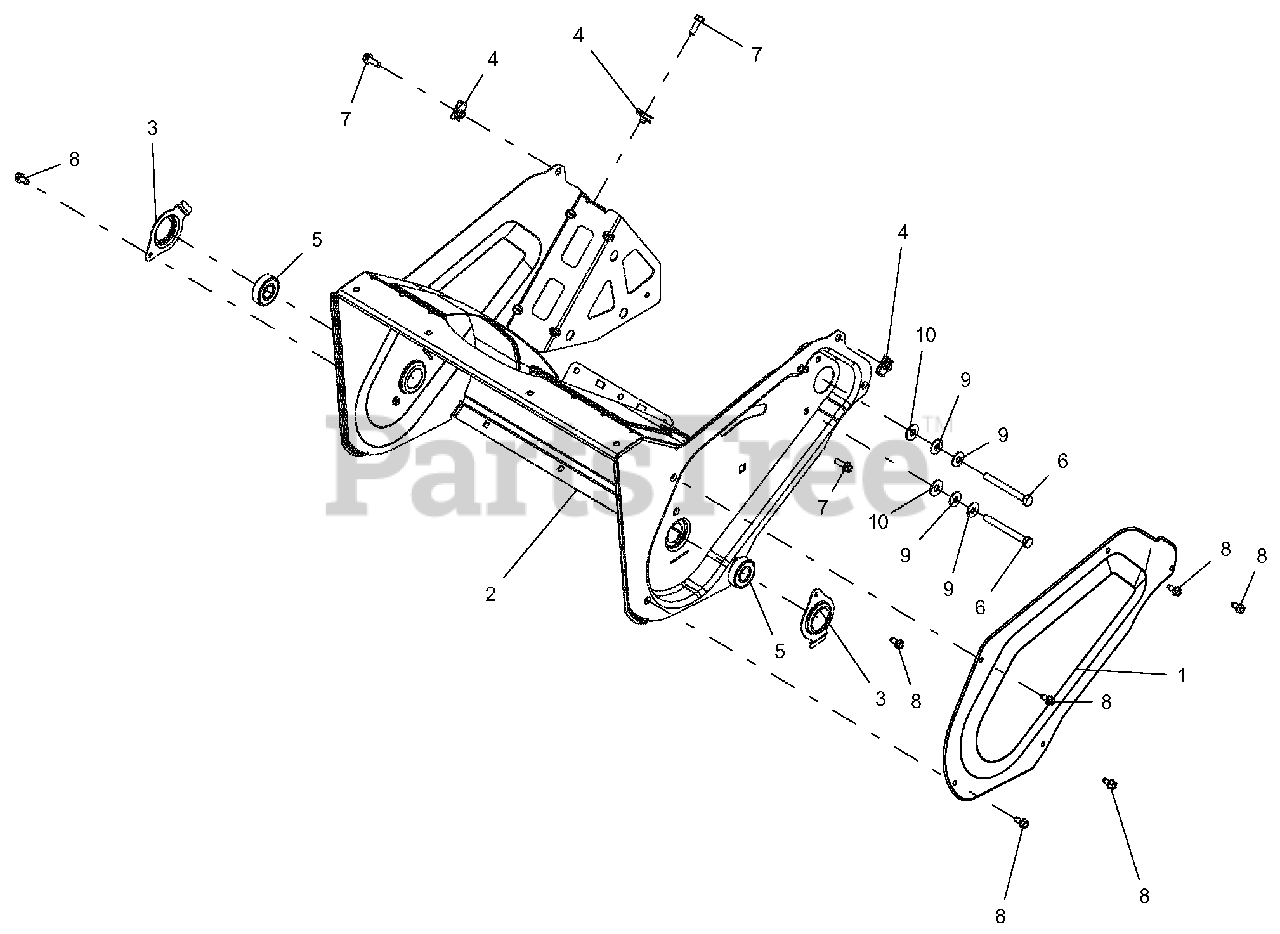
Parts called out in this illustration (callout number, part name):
1	COVER, BELT DRIVE HOUSING
2	WLDMT, FRAME
3	CAP, BRG
4	NUT-RTNR .25-20X.56
5	BRG-BALL .669X1.575X.47(6203Y)
6	@BLT-HEX .31-24X3.00 GR5 YWZC
7	BLT-HEX .25-20X.75 HWH YZ GR5
8	SCR-TAP .25-20X.50 HWH TR YWZ
9	WSHR,BLVL-.322X.813X.063
10	WSHR-HDND .375X.875X.064 YWZC
